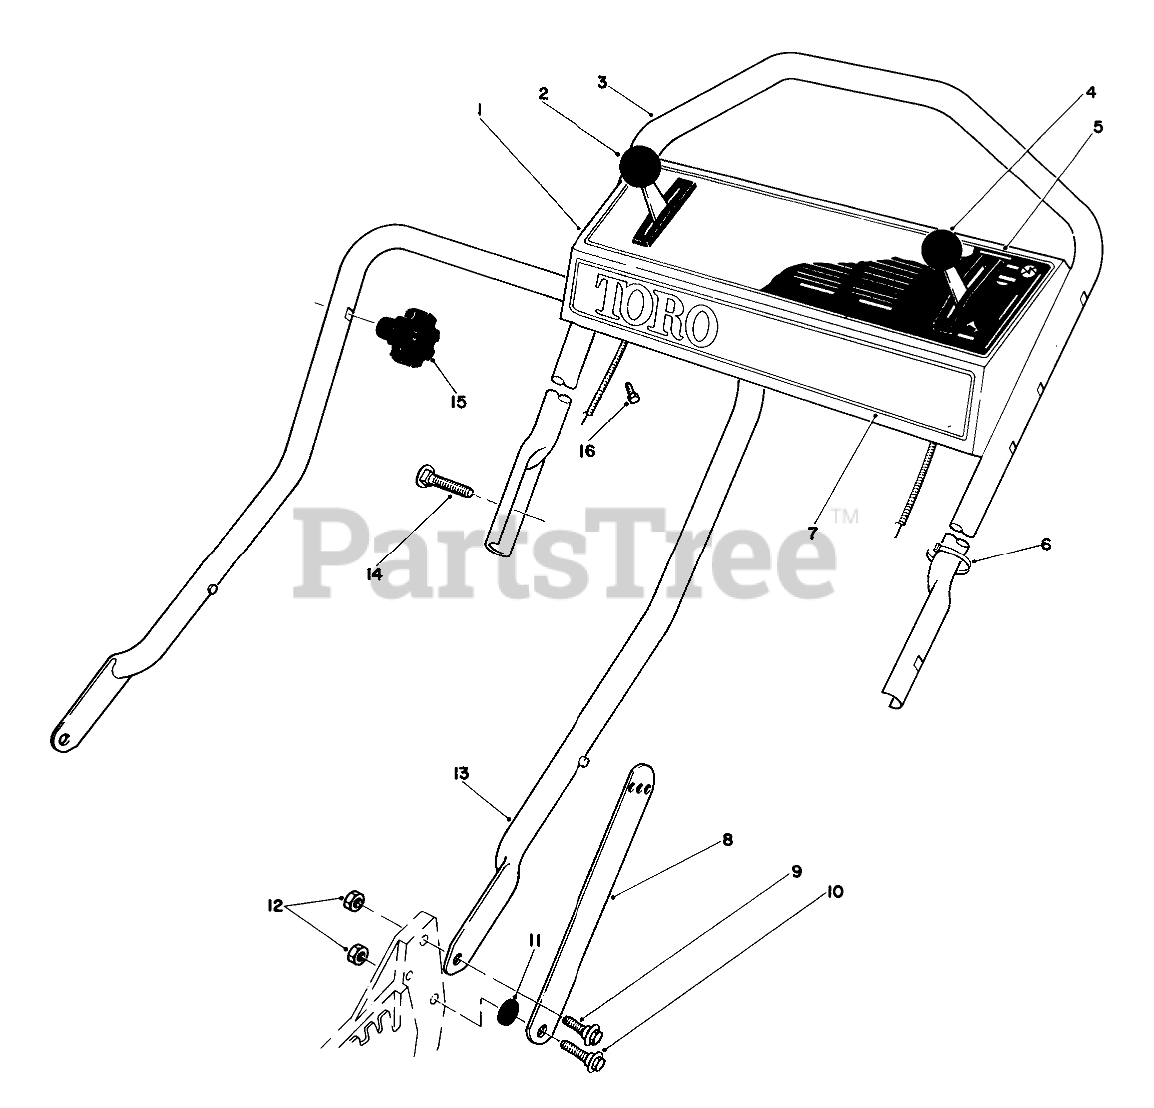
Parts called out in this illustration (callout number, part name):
1	Panel-Control (Incl. Ref. #5)
2	GROUND SPEED CONTROL
3	UPPER HANDLE
4	SERVICE THROTTLE CONTRO
5	Decal-Instruction Panel
6	TIE-CABLE
7	Decal-Toro
8	Handle Latch
9	SCREW-SHOULDER
10	SCREW-SHOULDER
11	SPACER
12	NUT-LOCK, NI
13	Handle-Lower
14	5/16-18 X 2 HNDLE SCREW
16	SCREW-HWHTF
